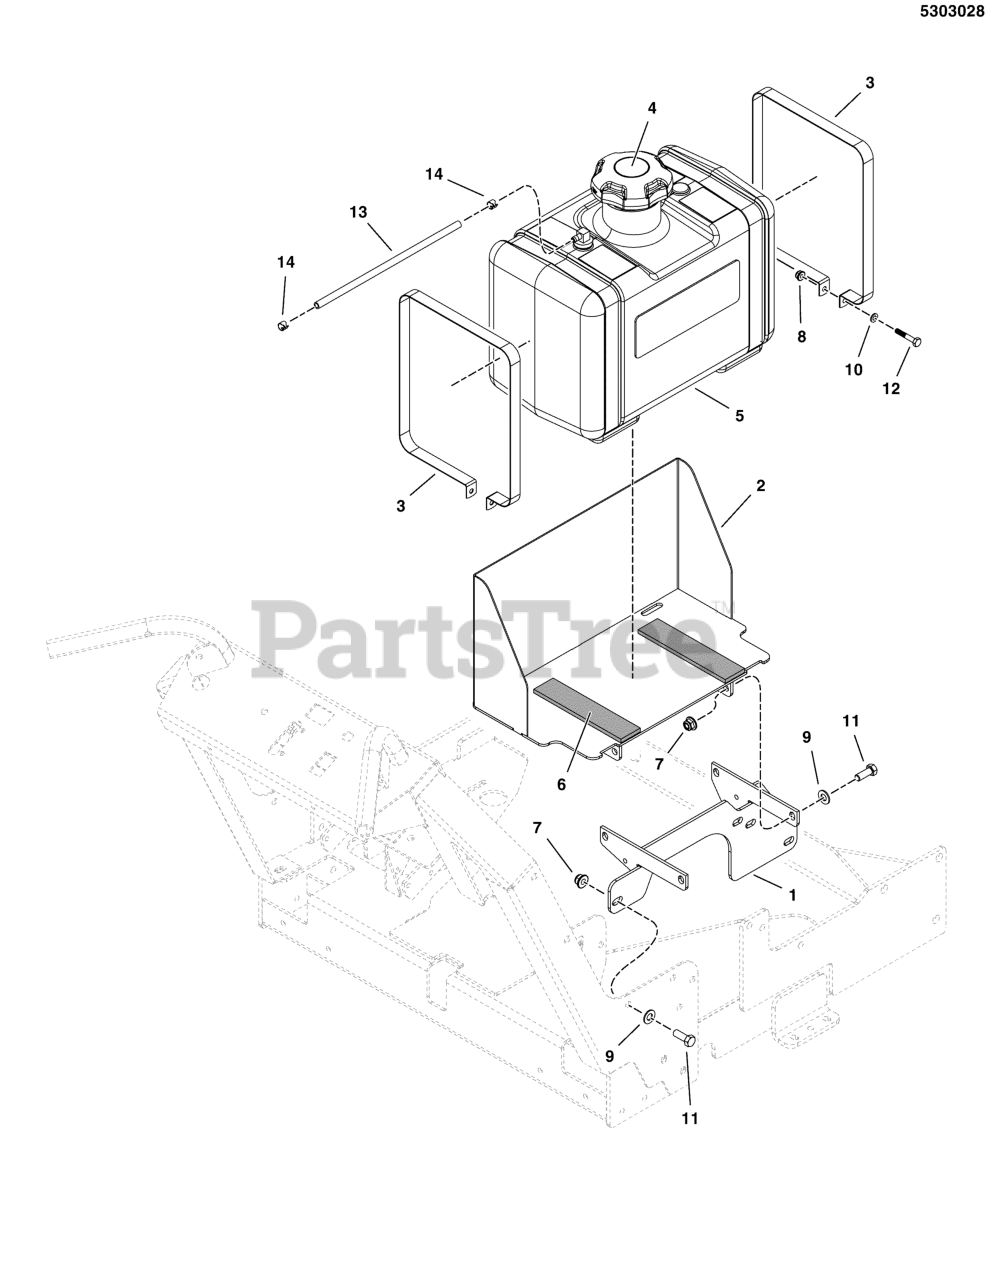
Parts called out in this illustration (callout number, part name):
1	WELD, LOWER FUEL TANK MOUNT - RED
2	WELD, TANK MOUNT, SW20-52-61 - RED
3	STRAP, FUEL TANK
4	FUEL CAP, 3-1/2", MANAGED VENT OUT, 12"
5	TANK, 5 GAL, W DROP TUBE/VENT
6	PAD, RUBBER MOUNT
7	NUT, 3/8-16 HEX NYLOCK FLANGE
8	NUT, 1/4-20 HEX NYLOCK FLANGE
9	WASHER, 3/8 SAE
10	WASHER, 1/4 SAE
11	BOLT, 3/8-16 X 1" GD5 CZ
12	BOLT, 1/4-20 X 1-1/2, GD5
13	HOSE, 1/4" FUEL, 12.00"
14	CLAMP, HOSE, EXTERNAL, 1/2 - RED
15	GROMMET
